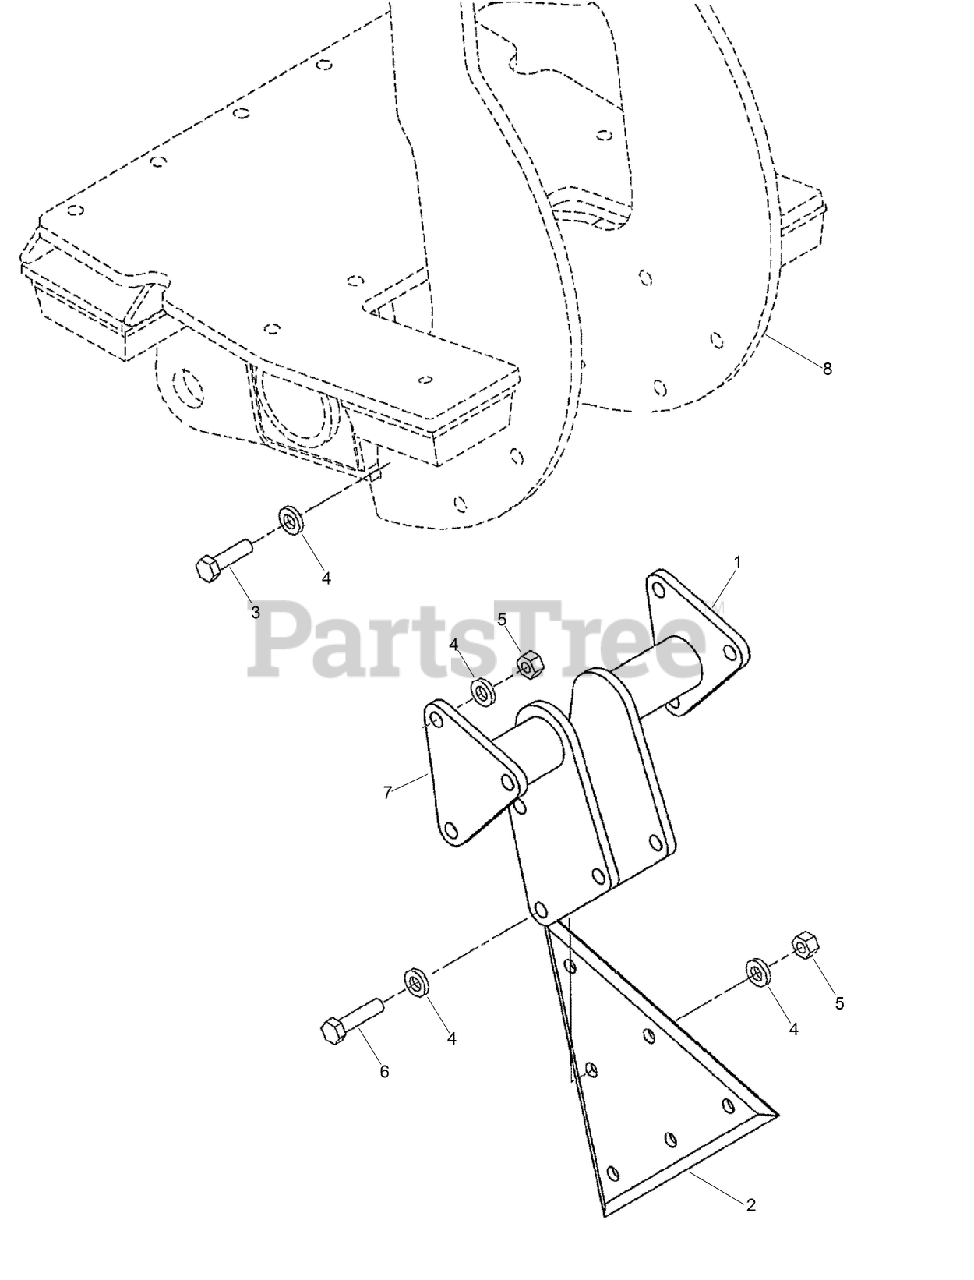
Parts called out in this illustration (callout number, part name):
1	BRACKET-mounting, sod cutter blade
2	BLADE-sod cutter
3	BOLT-Hex Hd 1/2 x 1-3/4 GR5 ZND
5	NUT-HEX
7	BRACKET-mounting, sod cutter blade
8	FRAME-plow gearbox mounting
